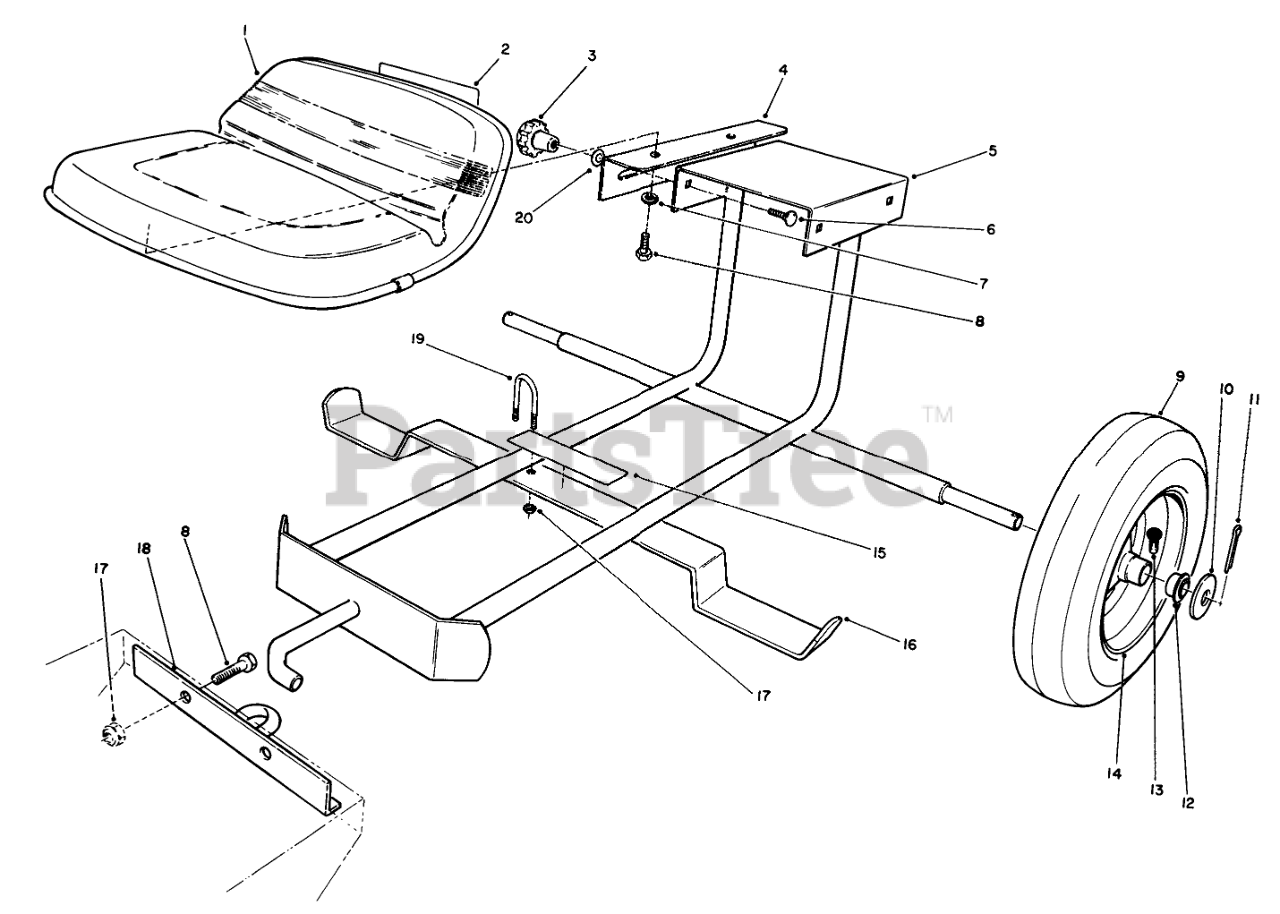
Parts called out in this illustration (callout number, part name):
1	Seat
2	DECAL
4	BRACKET R
5	Frame Assembly
6	BOLT-CARR
7	WASHER-LOCK
8	SCREW-HH
10	WASHER-FLAT
11	PIN-COTTER
12	BEARING
13	VALVE STEM-INNER TUBE
14	WHEEL
15	SULKY DECAL
16	SULKY FOOTREST R
17	NUT-LOCK, NI
18	HITCH
19	U-BOLT
20	WASHER-BELLEVILLE
